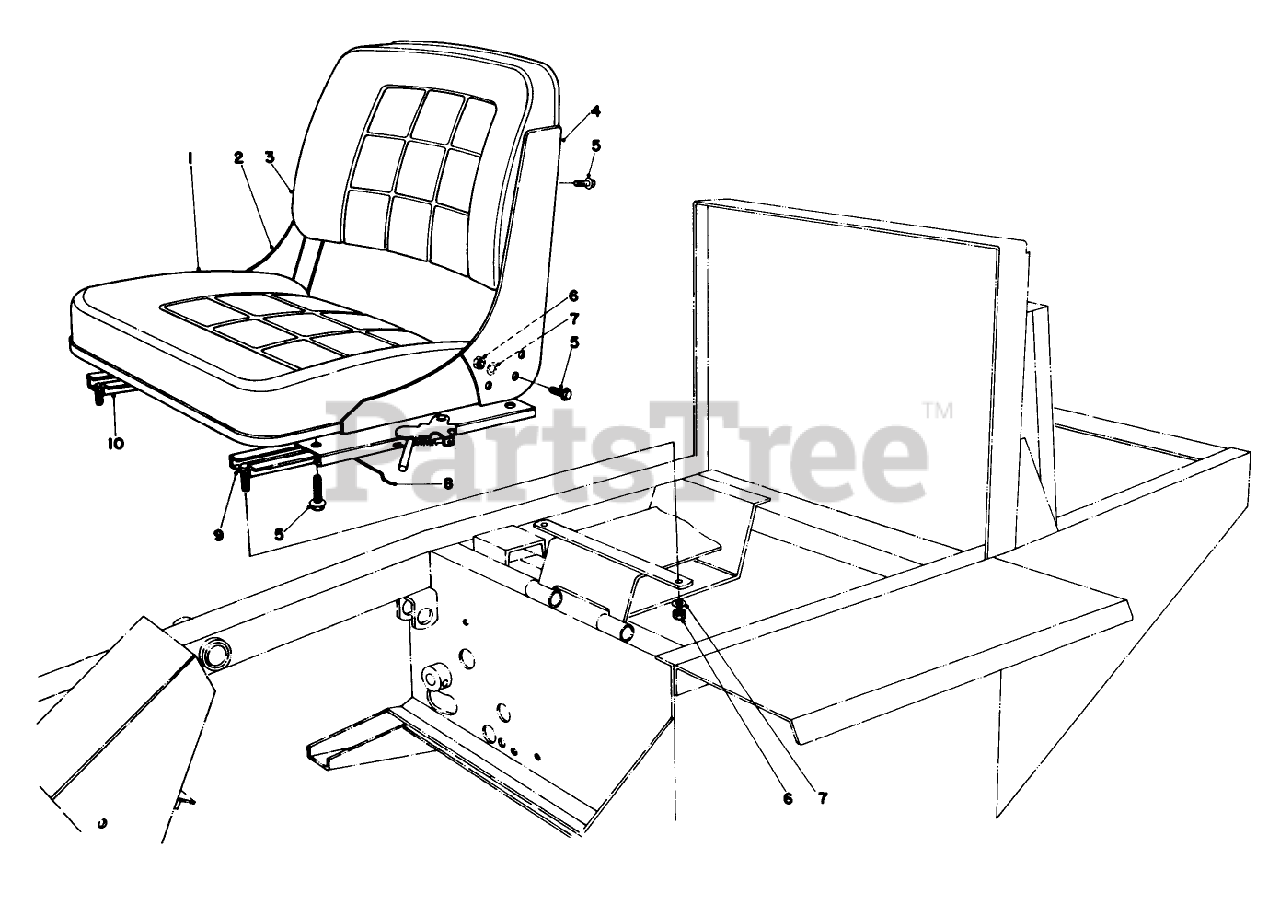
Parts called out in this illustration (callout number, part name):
1	Seat Cushion
2	RH RAIL
3	Backrest
4	Rail L.H.
5	SCREW-HHF
6	NUT-HEX
7	WASHER-LOCK
8	Connecting Rod
9	Adjuster L.H.
10	Adjuster R.H.
